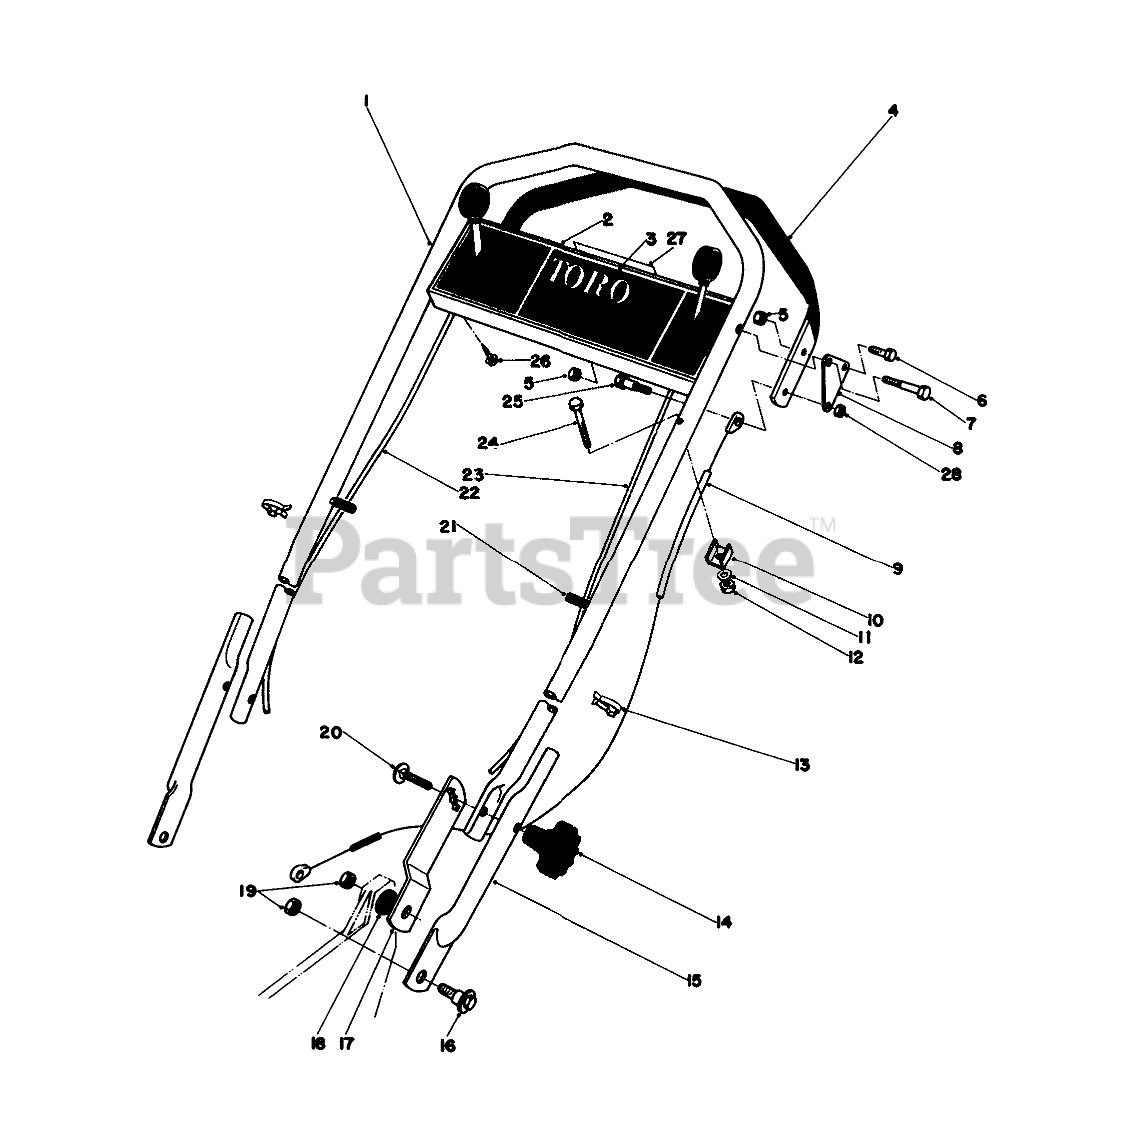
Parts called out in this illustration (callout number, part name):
1	Upper Handle
2	Control Plate
3	Decal-Control Panel
4	DEMAND HANDLE ASM
5	NUT-LOCK, CONE
6	SCREW-HH
7	BOLT-SHOULDER
8	Bracket Demand
9	DEMAND HAND CABLE
10	CLAMP-CABLE
11	WASHER-FLAT
12	NUT-LOCK, NI
13	BOWDEN CLIP
15	LOWER HANDLE
16	SCREW-SHOULDER
17	Handle Latch L.H.
18	SPACER
19	Nut
20	SCREW-CARR
21	CAP-VINYL
22	GROUND SPEED CONTROL
23	Throttle Control
24	SCREW-HH
25	Shoulder Bolt
26	SCREW-HWHTF
27	Decal-Select-a-Pace
28	NUT-HEX, SIDE DEFORM
